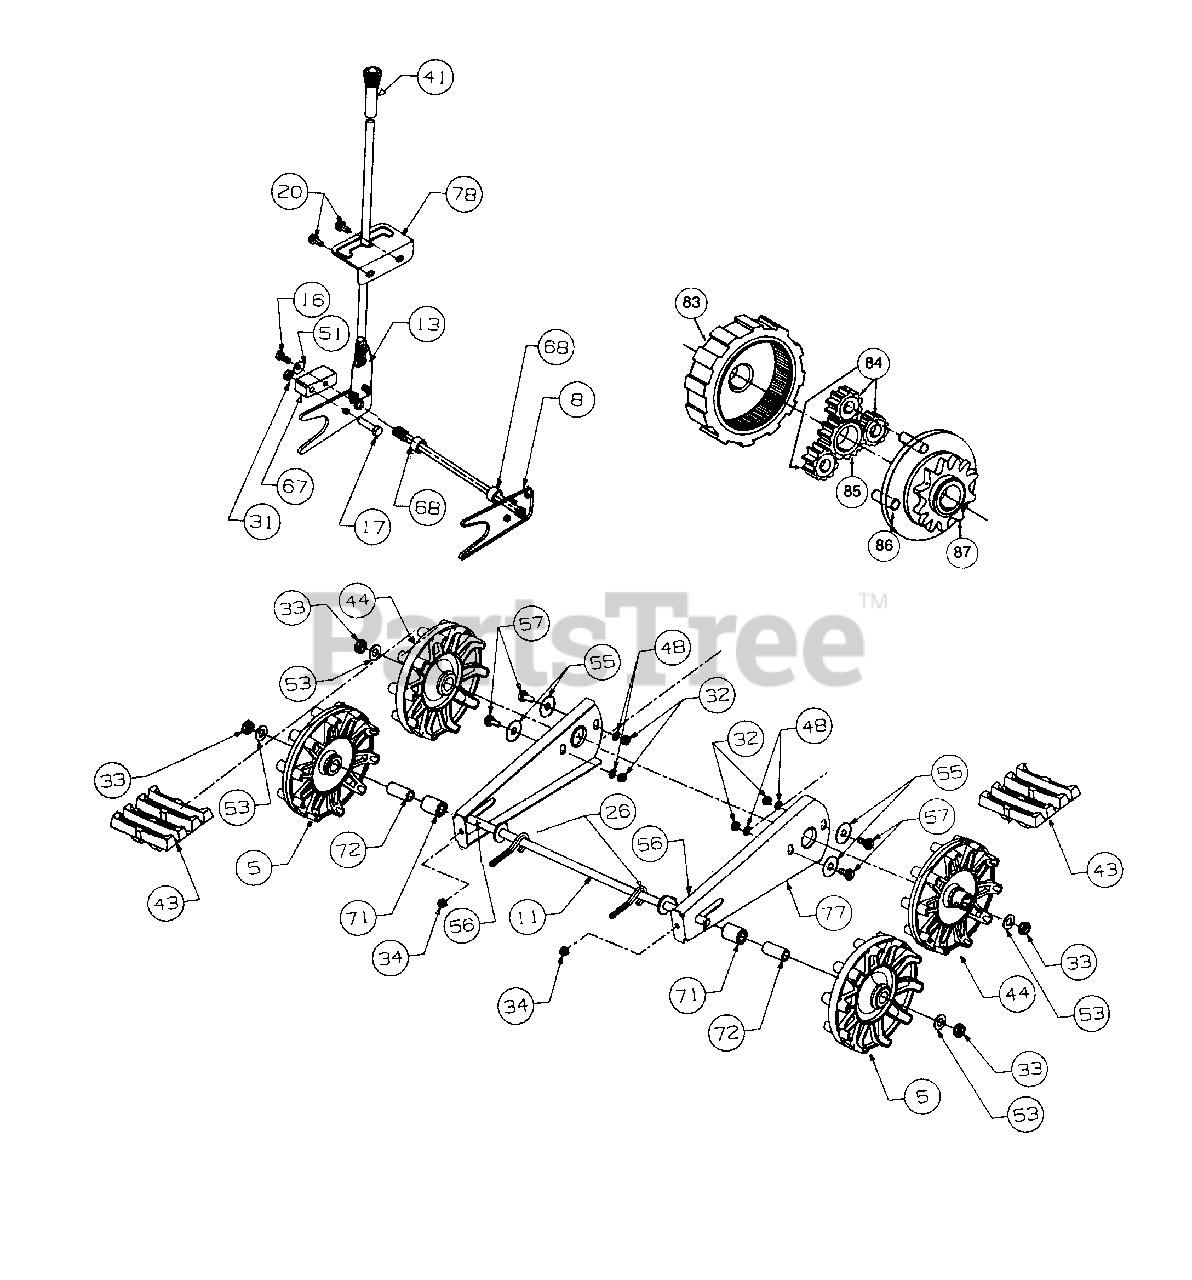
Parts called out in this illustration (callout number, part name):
5	Wheel Assembly Idler
16	Screw
17	Screw
20	Screw
26	Screw
31	Nut Lock
32	Nut Hex
33	Nut Jam
34	Nut Hex
43	Track
44	Wheel-Track Drive
48	Washer Lock
51	Washer-Bell
53	Washer-Flat
55	Washer-Flat
56	Lubricant
57	Screw-Shoulder
67	Lift-Shaft Drive
68	Spacer
71	Spacer
72	Spacer
83	Gear Ring
84	Gear 12-Tooth
85	Gear 18-Tooth
86	Pin Dowel
87	Carrier
